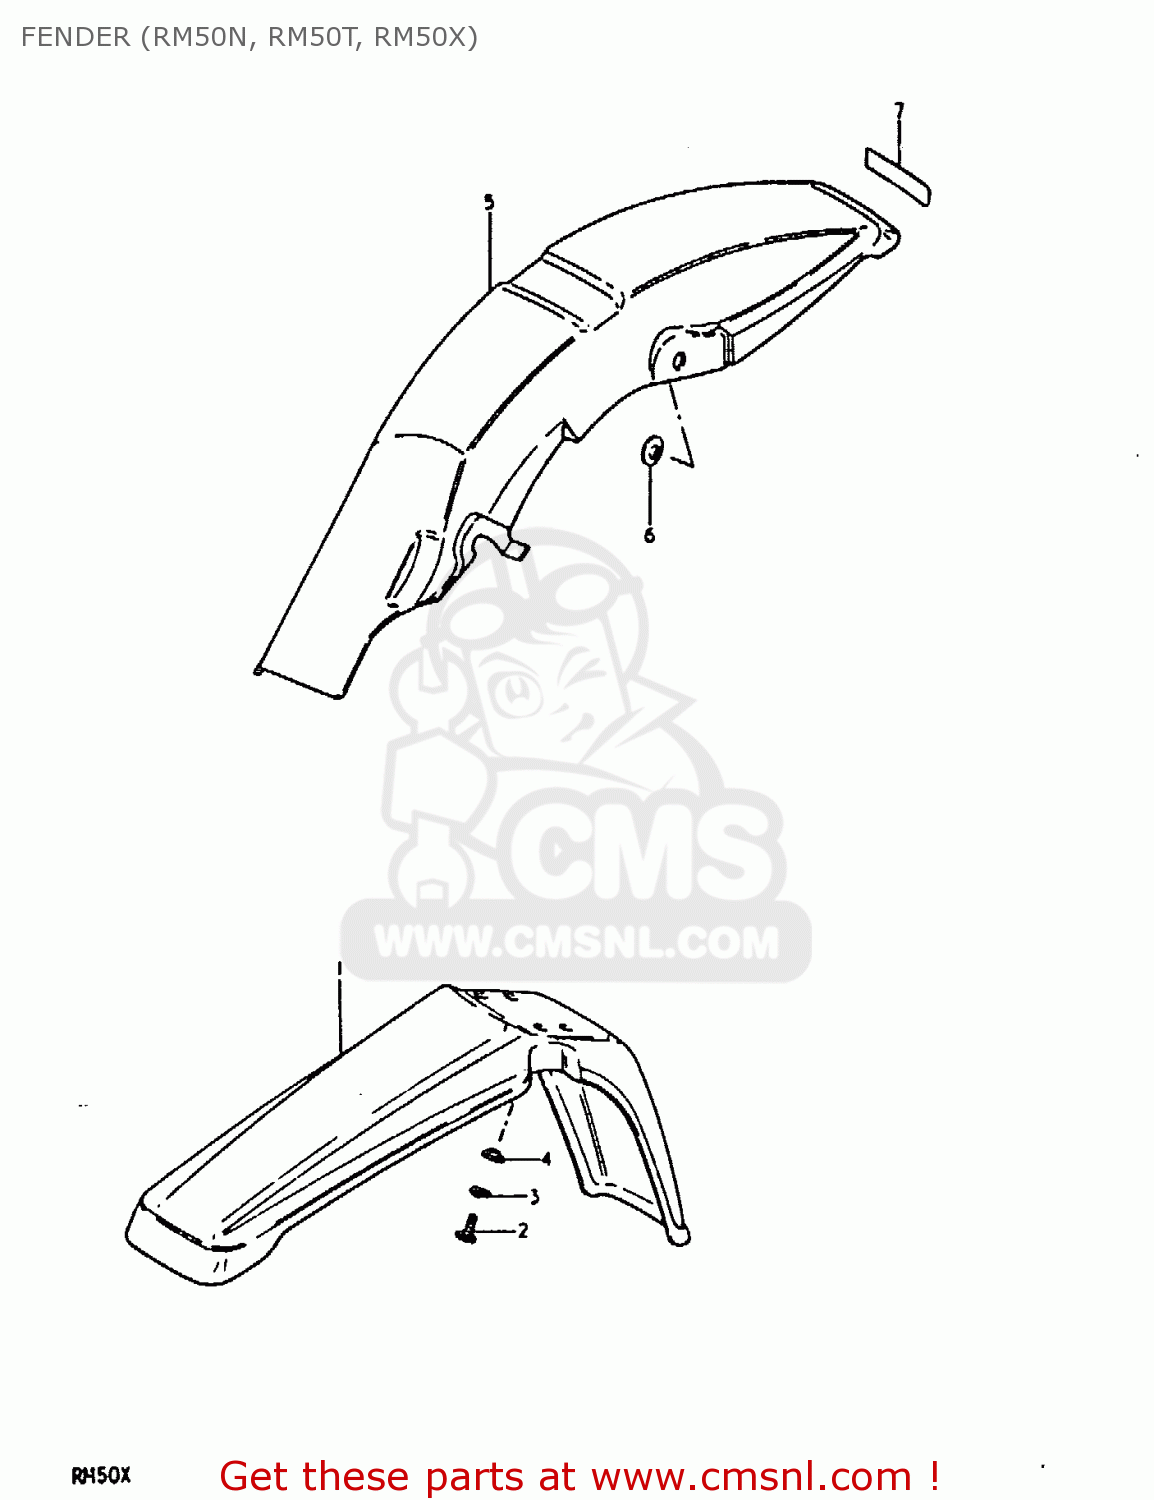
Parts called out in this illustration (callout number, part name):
1	FENDER,FRONT
2	BOLT, UPPER
3	LOCK WASHER
4	SPACER
5	FENDER,REAR
6	WASHER
7	EMBLEM,FRONT FENDER
